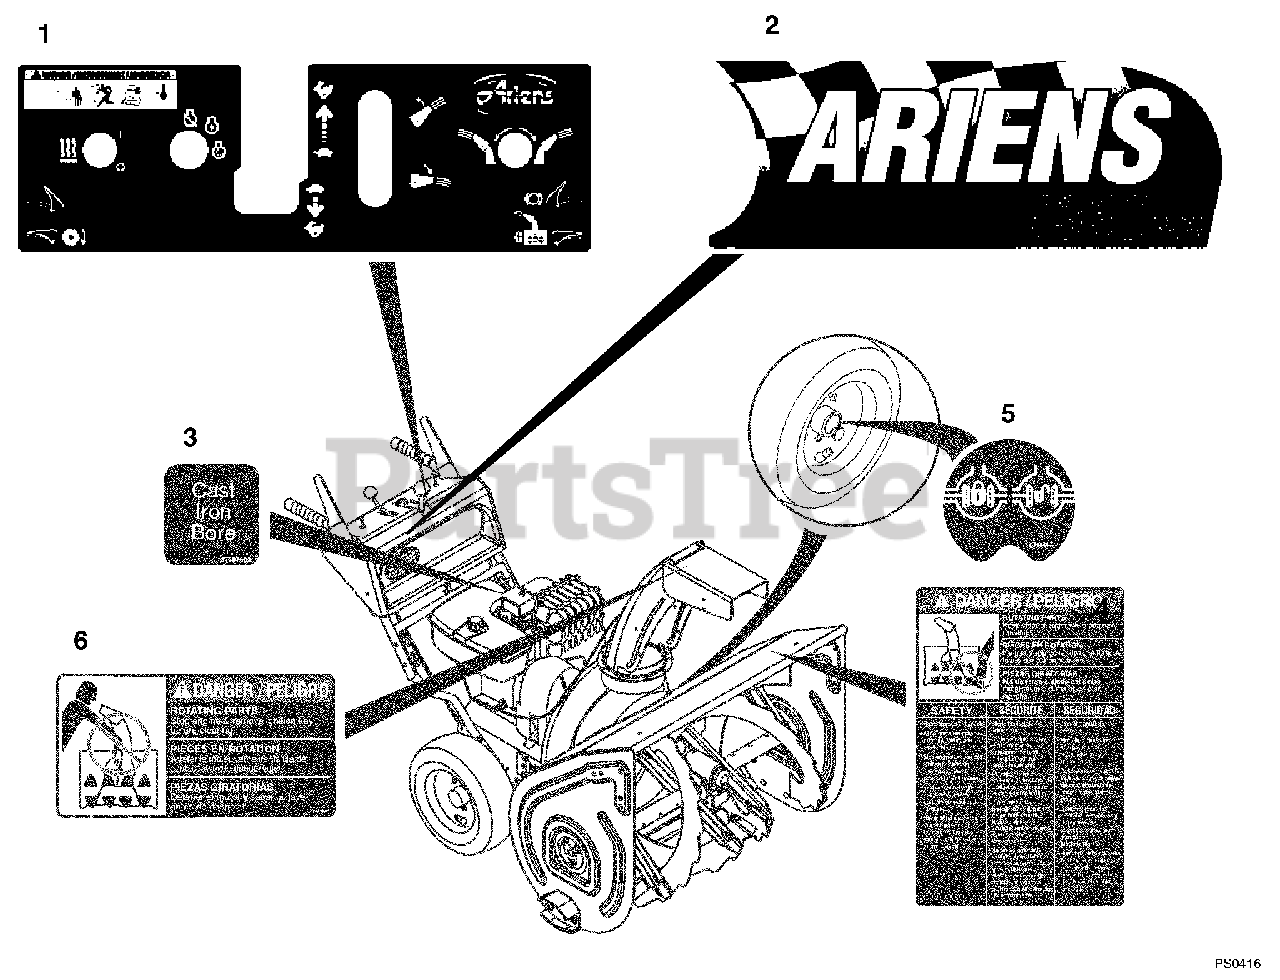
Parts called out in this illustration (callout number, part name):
1	DECAL, CONTROL - 1332, 1336
2	DECAL, FRONT PANEL - 1336
3	DECAL - CAST IRON BORE
4	DECAL, DANGER
5	DIFFERENTIAL LOCK DECAL
6	DECAL, DANGER - ROT. PARTS
